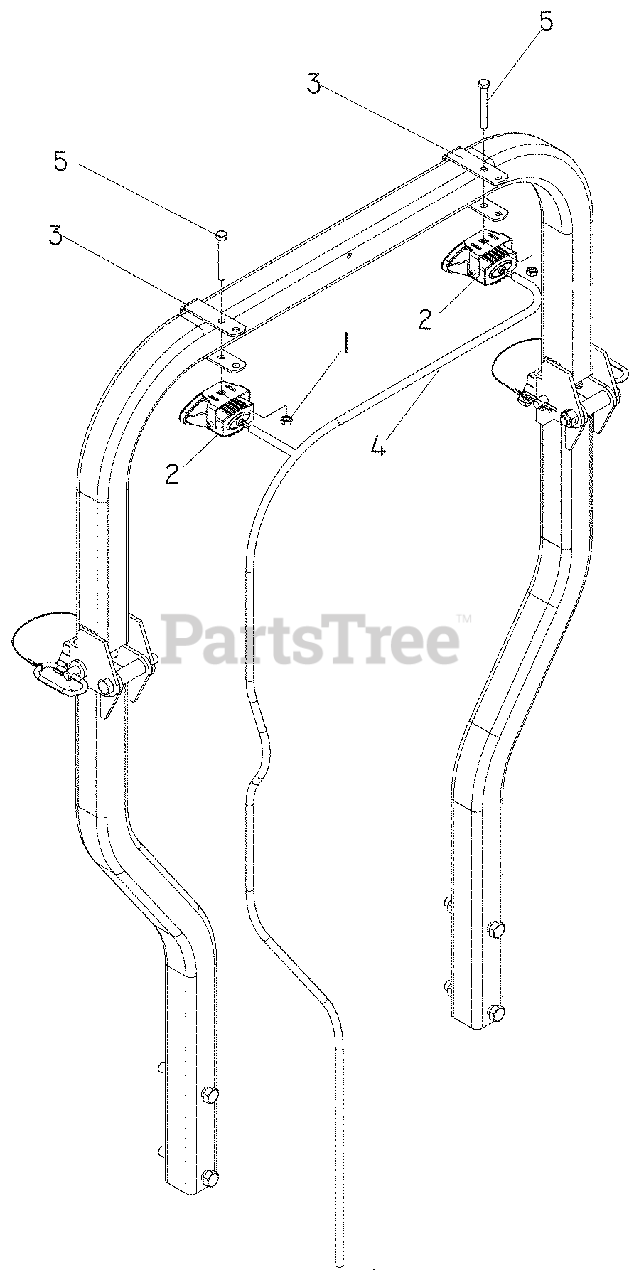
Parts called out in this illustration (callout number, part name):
1	NUT 5/16-18, JAM
2	LIGHT W/BRKT & HRDWARE
3	LIGHT MOUNTING BRACKET
4	LIGHT HARNESS
5	HCS, 5/16-18 x 2½
